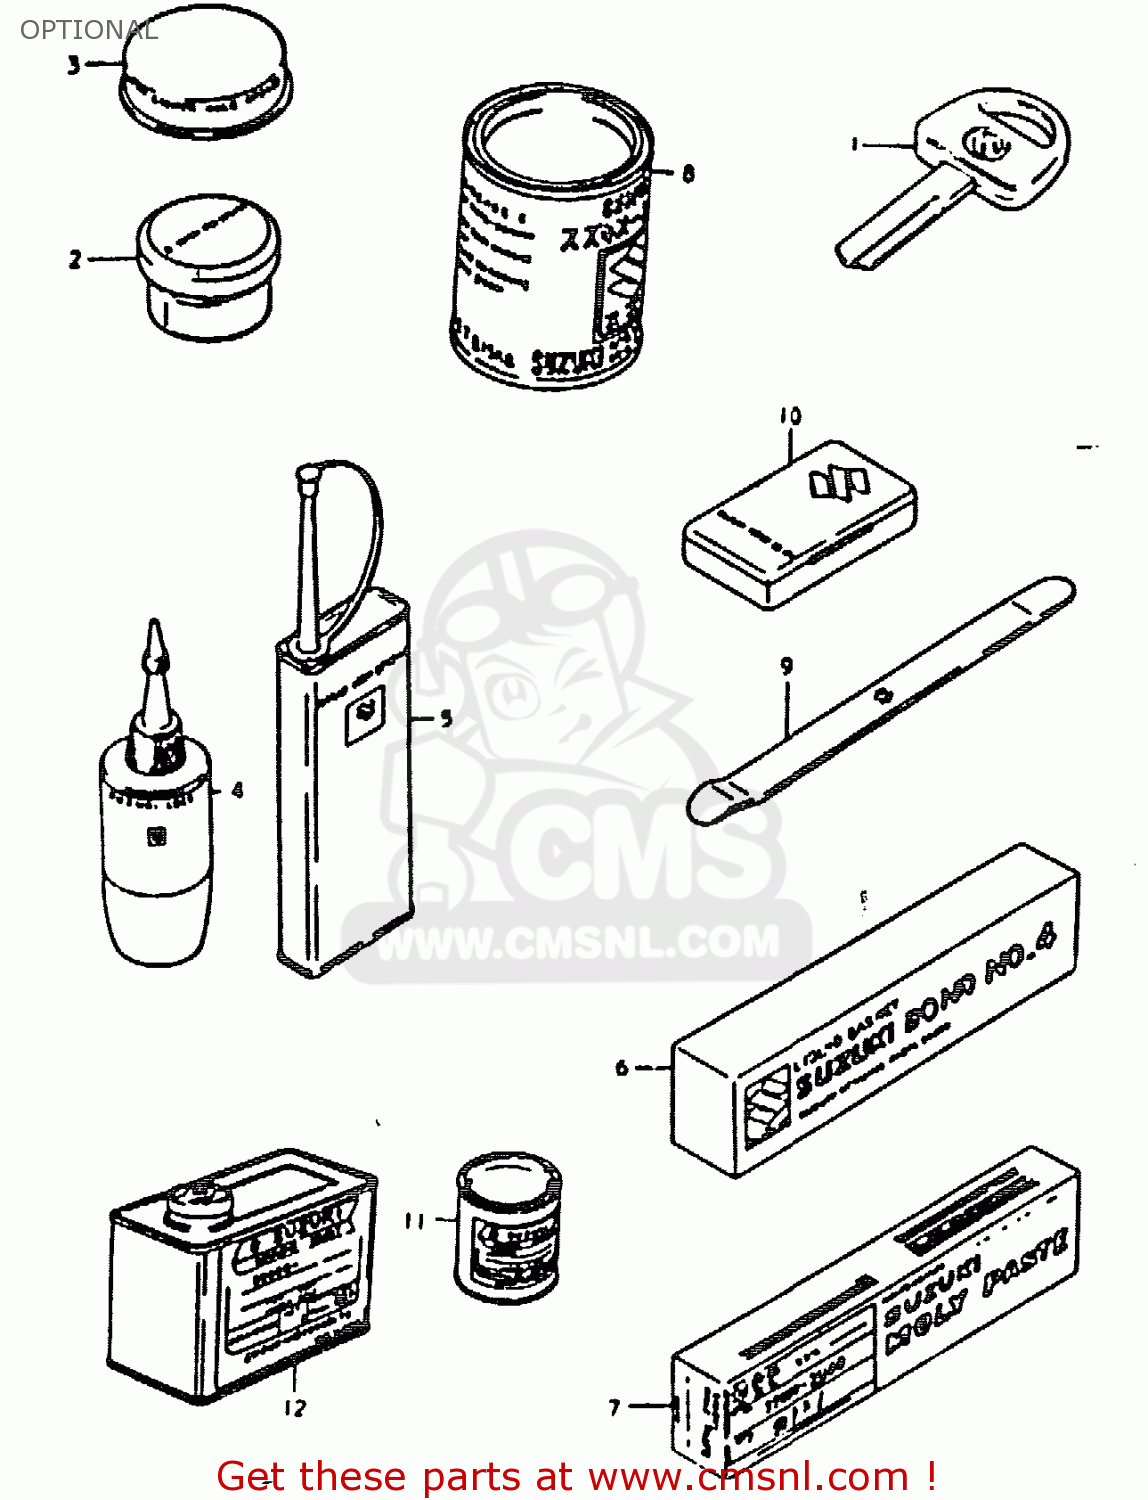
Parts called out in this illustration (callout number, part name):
1	KEY,BLANK
2	GREASE,PBC FOR BRK PAD 20G
3	GREASE,SILICON 20G
4	THREAD LOCK NO.1303B PURPL 50G
5	THREAD LOCK NO.1401 CLEAR 200G
6	BOND 1104
7	SUZUKI MOLY PASTE
8	GREASE(C)EP2 LITHIUM 150G
9	LEVER,TIRE
10	TUBE REPARING TOOL
11	PAINT,BLACK
12	PAINT (BLACK)
